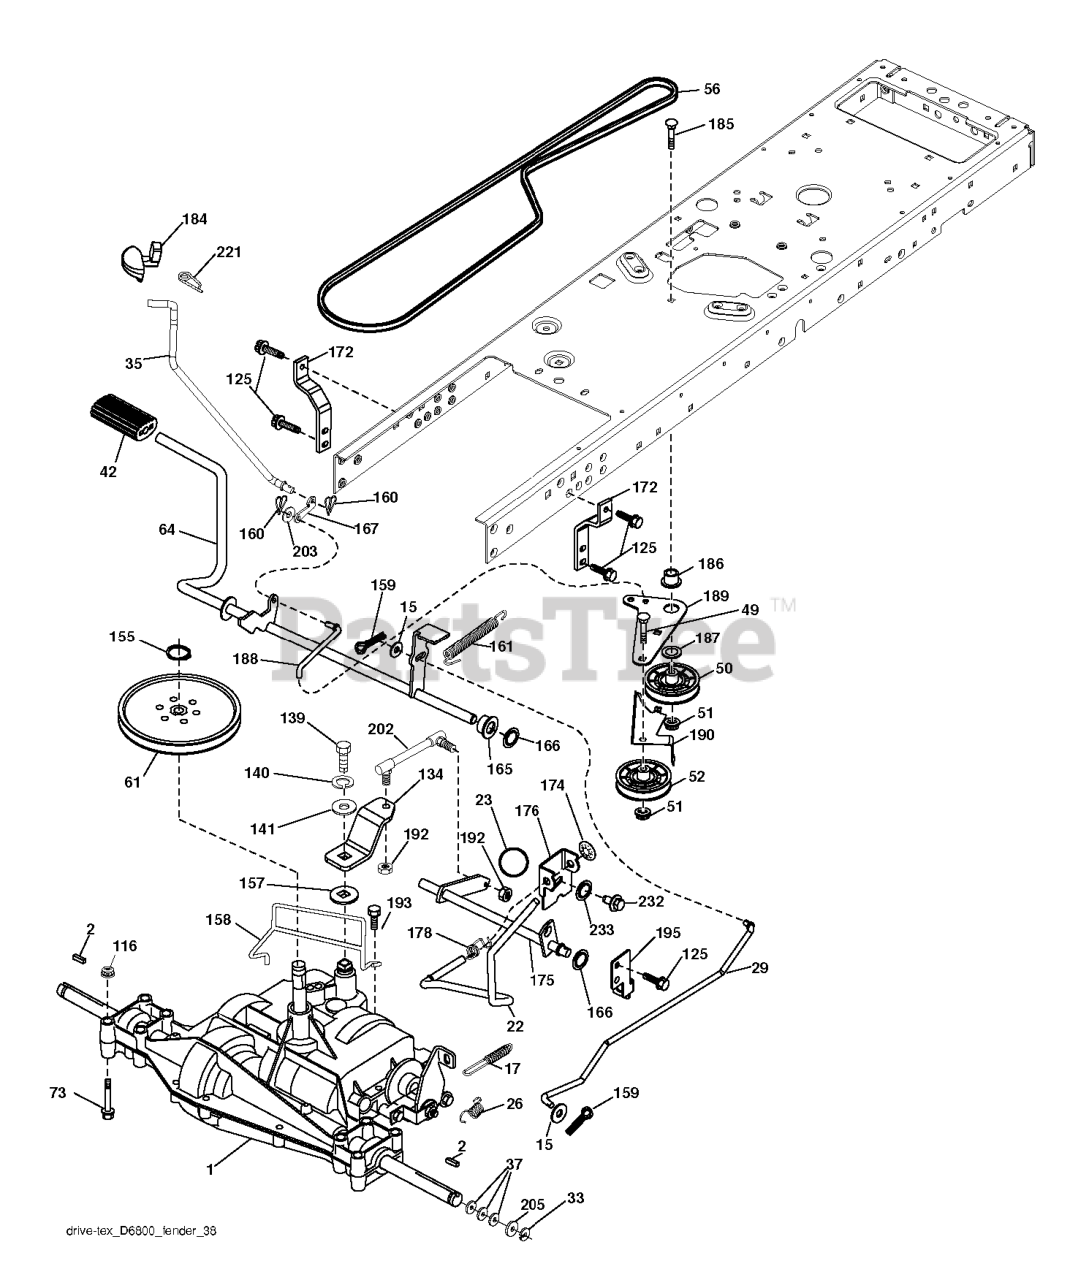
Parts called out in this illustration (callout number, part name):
2	SQUARE KEY
15	WASHER
17	SPRING.BRAKE.PEERLESS.TEX
22	ROD.SHIFT.FENDER.TLT.2006
23	KNOB.DUCKHEAD.1/2
26	SPRING.BRAKE.RTN.GR.DR
29	ROD.BRAKE.PEERLESS
35	ROD.CNTRL.PARK.PREDATOR.LT.TEX
42	PEDAL COVER T
50	IDLER.FLAT.910.OFFSET
51	NUT LOCK FLG 3/8-16 UNC
52	IDLER.V-GROOVE.910.OFFSET
56	V-BELT.TRACTOR.DRIVE.P
64	SHAFT.ASM.PEDAL.BRAKE.
73	BOLT HEX 5/16-18 GR 5
116	NUT LOCK HEX FLANGE 5/16-18
125	SCREW
134	ARM.SHIFT.
139	BOLT 1/4-28X3/4
140	LOCKWASHER
155	RETAINING RING LT
157	WASH-SHFT PLT LT
158	KEEPER.PMS.18/20.D4365
159	COTTER PIN
160	RETAINER CLIP
161	SPRING, RETURN LT
165	BUSHING.SHAFT.BRAKE.HAND
166	NUT.PUSH.625.2006
167	LATCH.BRAKE.SPRING
172	STRAP.TRQ.LH.GEAR.DRIV
174	NUT.PUSH.500.2006
175	SHAFT.ASM.SHIFT.
176	ARM.CLEVIS.ROD.SHIFT
178	SPRING.SHIFT.GT2006
184	HANDLE PARKING BRAKE
186	SPACER.RETAINER
187	WASHER 12/32X2X10GA
188	RP.LINK.CLUTCH.GROUND.DRIVE
189	BELLCRANK.GROUND.DRIVE.TEX.
190	KEEPER.BELLCRANK.DRIVE
192	NUT LOCK CENTER 1/4 -28 FNTHD
193	SCREW 5/16"
195	BRKT.ROD.BRAKE.PEERLES
202	LINK.TRANSAXLE.D6800.18/20"TEX
203	WASHER
221	RETAINER.SPRING.CLIP.H
232	BOLT FIN HEX 7/16-14 X 1
233	WASHER SERRATED
